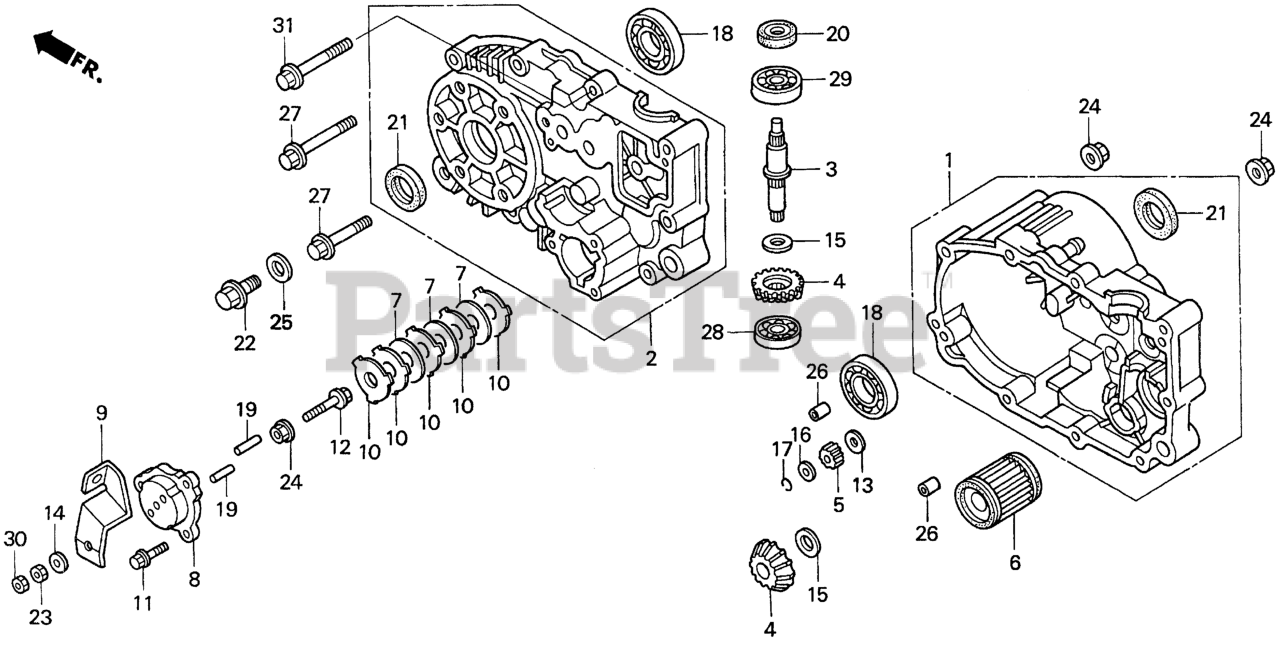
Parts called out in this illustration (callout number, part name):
1	CASE, R. TRANSMISSION
2	CASE, L. TRANSMISSION (NA USE ALT:20001-VE3-010)
3	SHAFT, INPUT
4	GEAR, BEVEL
5	GEAR, IDLE DRIVE
6	FILTER, SUCTION
7	PLATE, BRAKE FRICTION
8	COVER, BRAKE
9	ARM, L. BRAKE
10	PLATE, BRAKE
11	BOLT, FLANGE (6X18)
12	BOLT, FLANGE (8X45)
13	WASHER (12MM)
14	WASHER (8MM)
15	SHIM A, BEVEL GEAR
15	SHIM B, BEVEL GEAR
15	SHIM C, BEVEL GEAR
15	SHIM D, BEVEL GEAR
15	SHIM E, BEVEL GEAR
15	SHIM F, BEVEL GEAR
15	SHIM G, BEVEL GEAR
15	SHIM H, BEVEL GEAR
15	SHIM I, BEVEL GEAR
15	SHIM J, BEVEL GEAR
15	SHIM K, BEVEL GEAR
16	WASHER, THRUST (10.2X16X1)
17	CLIP B, BEARING
18	BEARING, RADIAL BALL
19	ROLLER (8X35)
20	OIL SEAL (15X24X5)
21	OIL SEAL (19X41.3X9.5)
22	BOLT, DRAIN PLUG (12MM)
23	NUT, HEX. (8MM)
24	NUT, FLANGE (8MM)
25	WASHER, DRAIN PLUG (12MM)
26	PIN A, DOWEL (8X10)
27	BOLT, FLANGE (8X70)
28	BEARING, RADIAL BALL (6000)
29	BEARING, RADIAL BALL (6302)
30	NUT, U (8MM)
31	BOLT, FLANGE (8X50)
